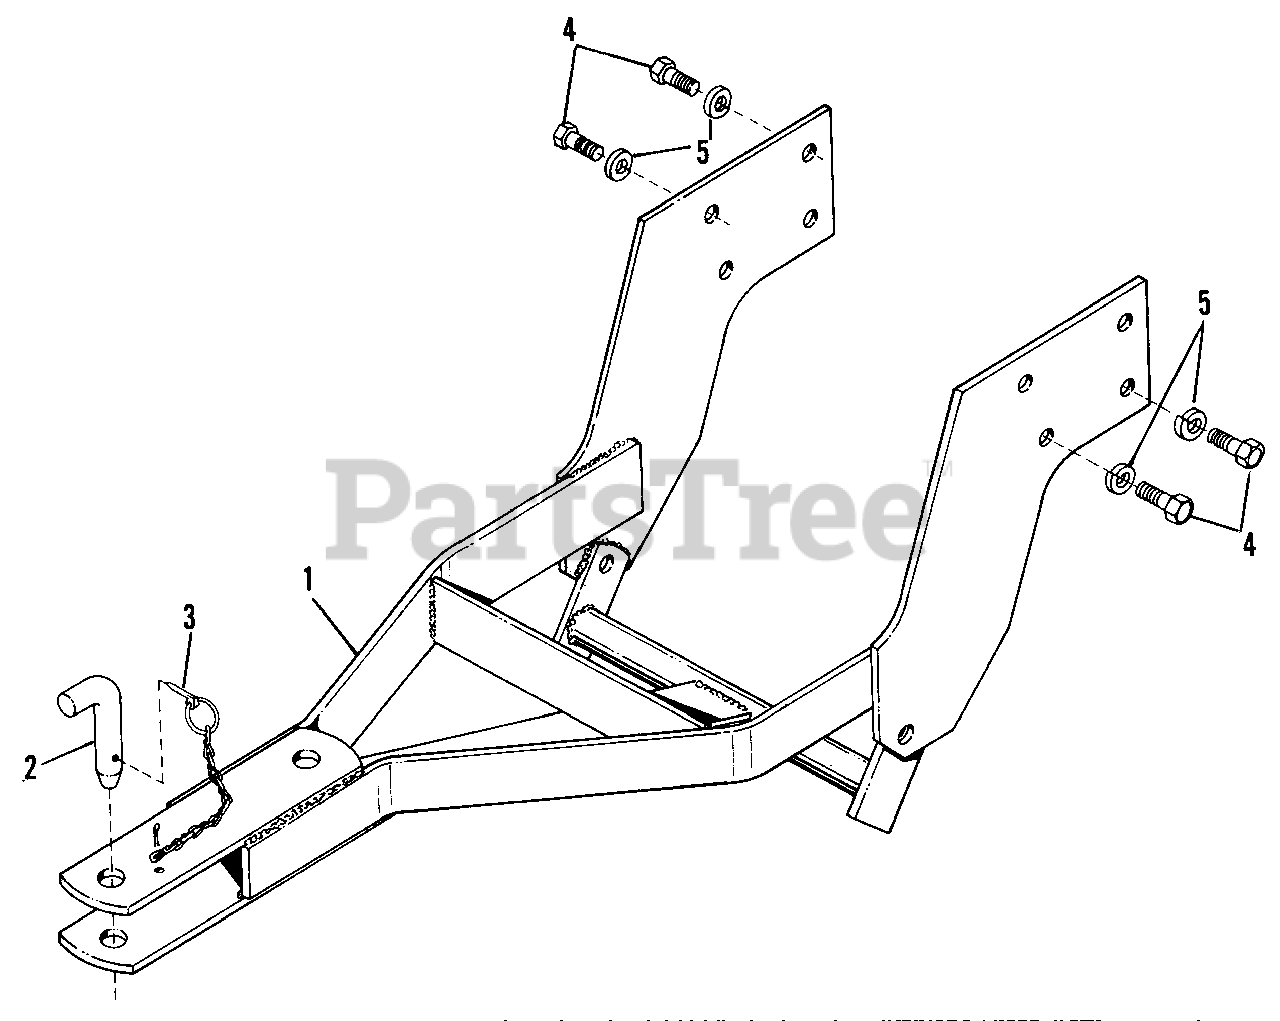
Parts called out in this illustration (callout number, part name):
1	Airplane Hitch Assy.
2	Pin Hitch
3	Ring Retainer
4	Hex Capscrew
5	Lock Washer
